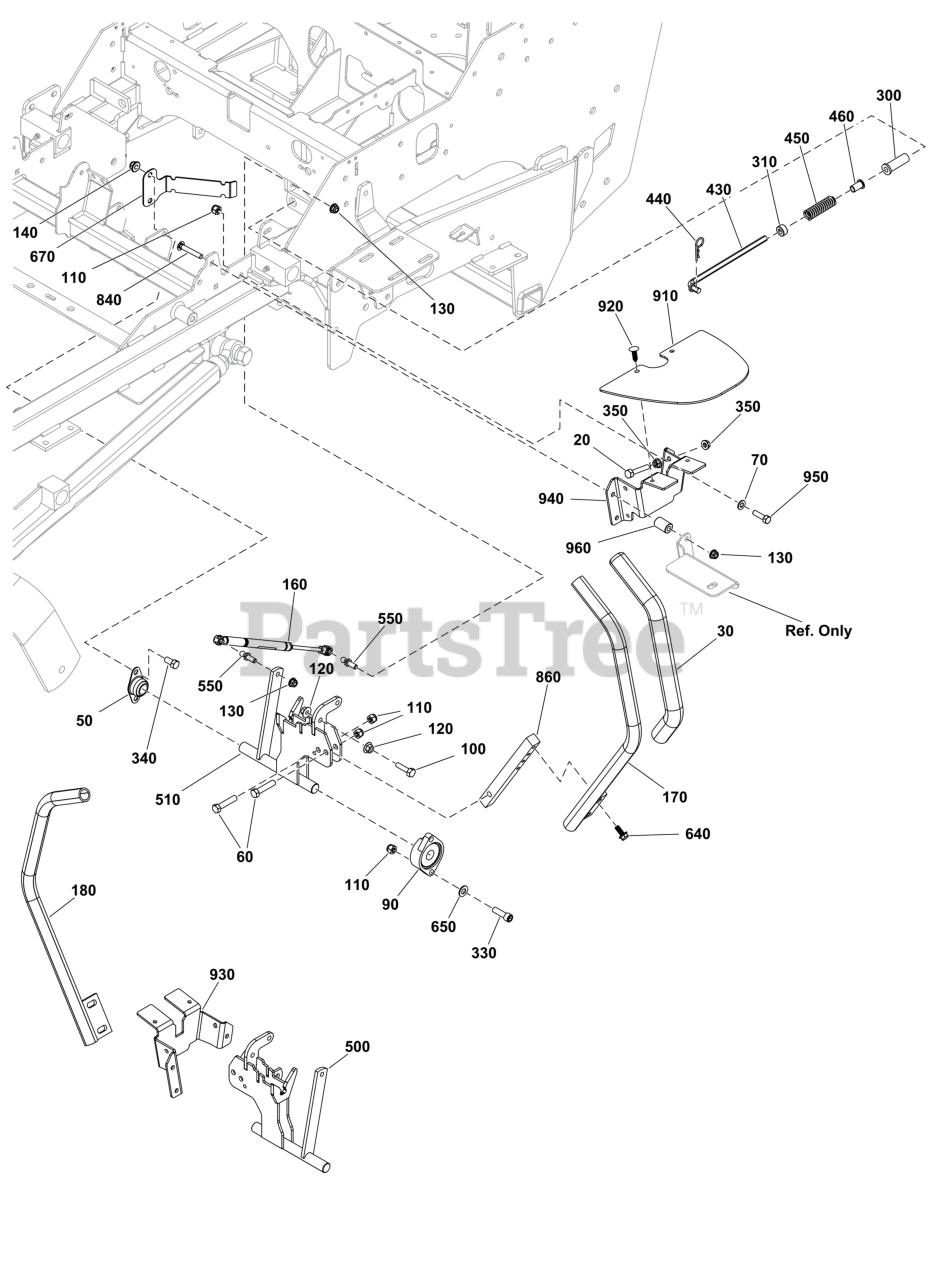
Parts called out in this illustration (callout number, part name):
20	BOLT, 5/16-18 X 1-3/4
30	GRIP
50	BEARING, BRONZE FLANG
60	BOLT, 3/8-16 X 1-3/4"
70	WASHER
90	BEARING, FLANGE
100	BOLT, 5/16-18 X 1-1/4
110	NUT, 3/8-16 HEX NYLON
120	NUT, 5/16-18 HEX SERR
130	NUT
140	NUT, 3/8-16 HEX NYLOCK
160	DAMPNER, CONTROL
170	CONTROL, HANDLE
180	CONTROL, HANDLE
300	BUSHING, FLANGED, 3/8
310	COLLAR, 3/8" SET
330	BOLT, 3/8-16 X 1-1/4
340	BOLT, 3/8-16 X 3/4" G
350	NUT, 5/16-18 HEX SERR
430	ROD, NEUTRAL
440	PIN, HAIR, .0915 X 1-7/8
450	SPRING, REVERSE RETUR
460	BUSHING, NYLON
500	SHAFT-CONTROL
510	SHAFT-CONTROL
550	10MM BALL STUD, 5/16-
640	SCREW, 5/16-18
670	BRACKET, HARNESS MOUNT, 2100 - BLK
840	BOLT, 5/16-18 X 1-3/4, CARRIAGE
860	MOUNT, CONTROL ARM
910	GUARD, RUBBER MOTION CONTROL
920	PUSH RIVET (TREE TYPE
950	BOLT, 5/16-18 X 3/4"
960	SPACER, .33 X .50X.50
